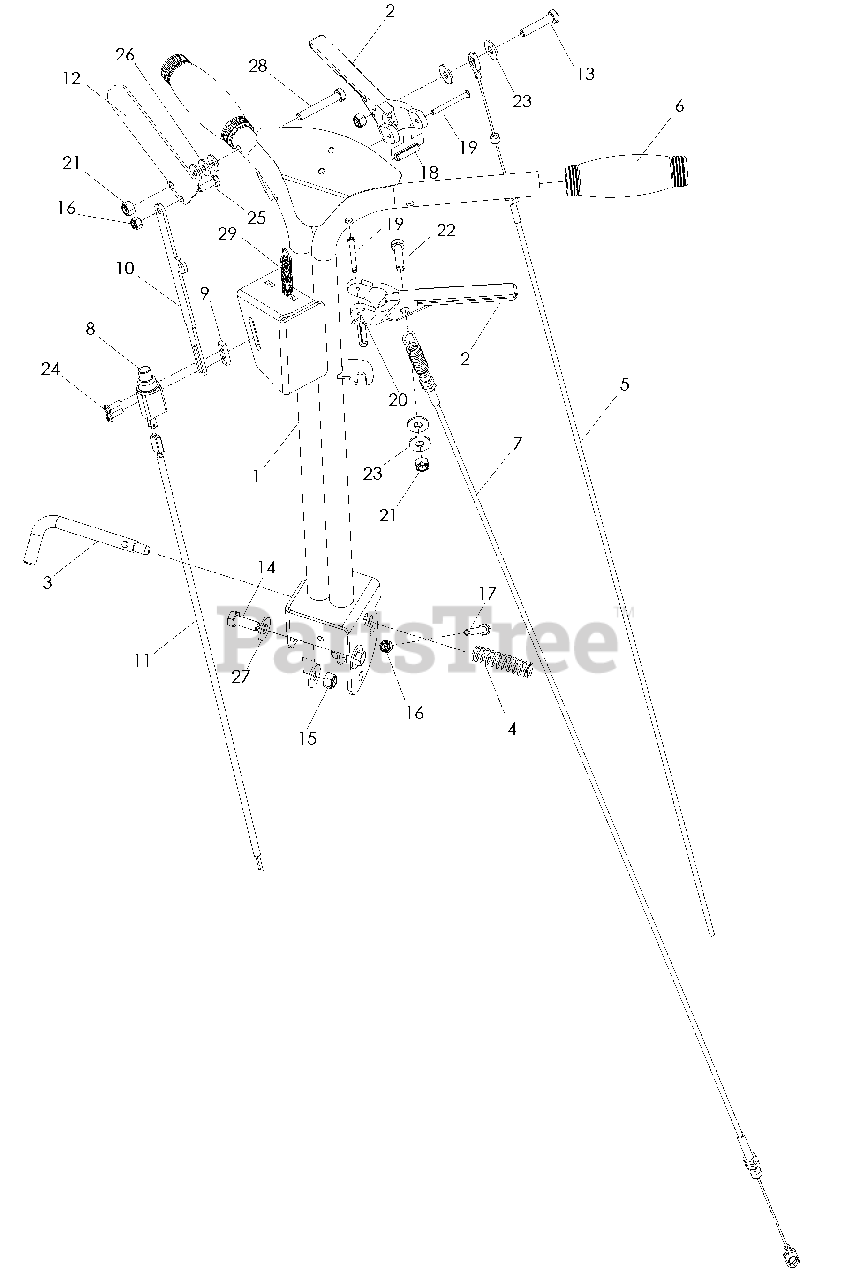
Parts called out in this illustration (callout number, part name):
1	HANDLE, ORANGE
2	LEVER, DRIVE
3	PIN, SPRING
4	SPRING, COMPRESSION
5	CABLE, THROTTLE
6	GRIP, HANDLE
7	CABLE, DEPTH
8	SWITCH, PLUNGER
9	PLATE, TAPPED
11	WIRE HARNESS
13	HCS 5/16-18 x 1 1/2
14	HCS 3/8-16 x 1
15	NUT 3/8-16 HEX NYLOC
16	NUT 1/4-20 HEX NYLOC
17	HCS 1/4-20 x 2
19	PIN, CLEVIS
20	COTTER PIN 3/32 x 3/4
21	NUT 5/16-18 HEX NYLOC
22	HCS 5/16-18 x 1 1/4
23	WASHER 5/16 STD FLT
24	SCREW #10-24 x .625
25	HCS 1/4-20 x 3/4
26	WASHER 1/4 FLAT
27	WASHER 3/8 STD FLT
28	HCS 5/16-18 x 2
